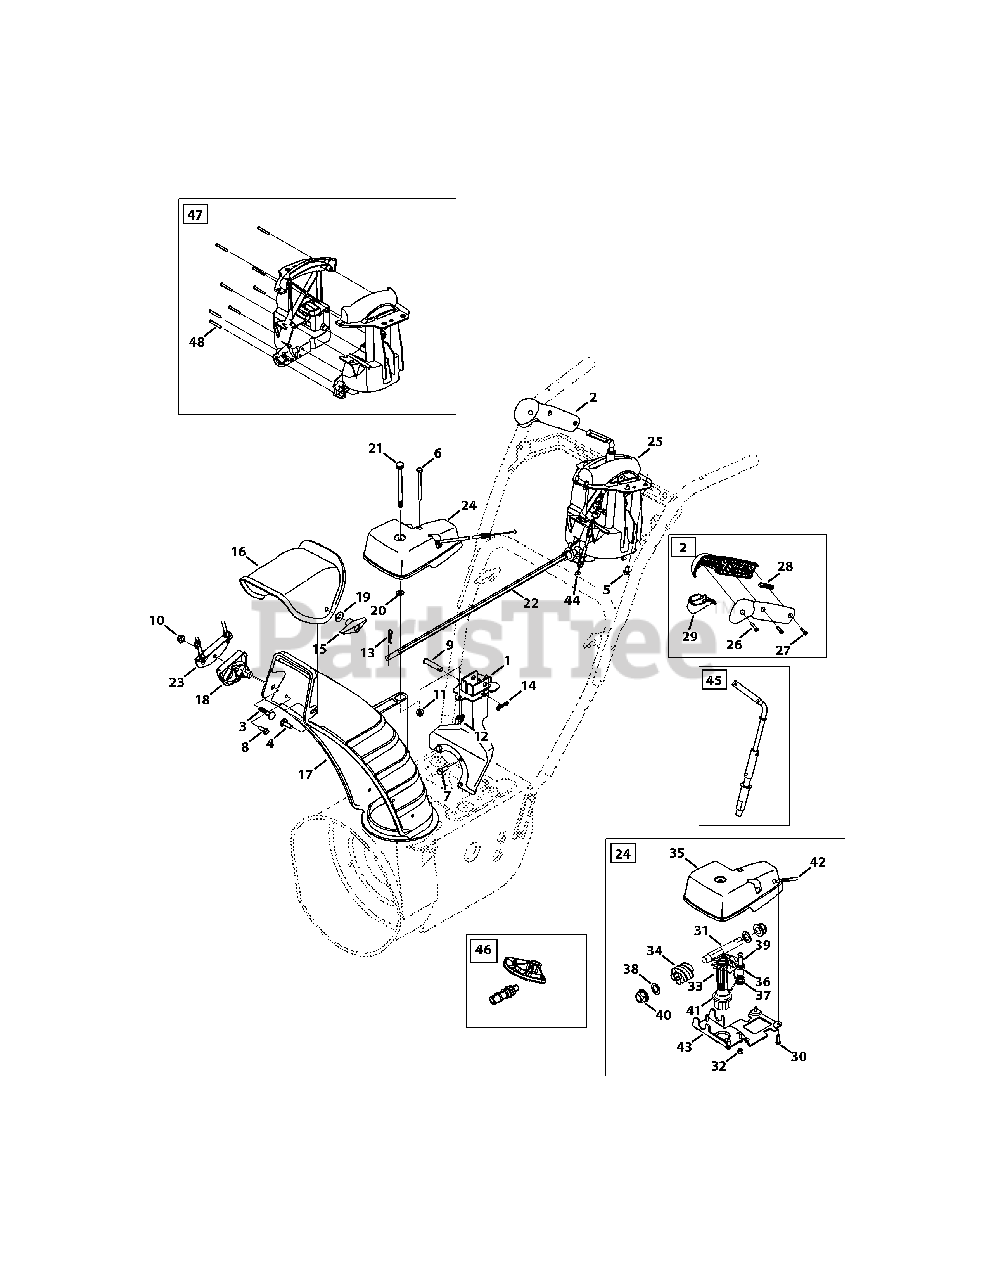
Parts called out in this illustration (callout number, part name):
1	Chute Support Bracket
2	Handle Assembly
3	Bolt, Carriage, 5/16-18 x 1.50
4	Bolt, Carrier, 5/16-18 x 1.00
5	Screw, HL, 1/4-15 x 0.50
6	Hex Head Screw, 1/4-20 x 3.00
7	Hex Head Screw, 5/16-24 x .750
8	Screw, HL, 1/4-15 x 0.750
9	Clevis Pin, 3/8 x 1.87
10	Nut, Flangelock, 5/16-18
11	Nut, Flangelock, 1/4-20
12	Wing Nut, 1/4-20
13	Internal Cotter Pin
14	Bow-Tie Cotter Pin
15	Star Knob, 5/16-18
16	Chute, Upper
17	Chute, Lower
18	Cable Guide, Chute Tilt
19	Washer, Flat, .349 x .879
20	Washer, Flat, .25 x .630
21	Screw, Shoulder, .312 x 3.5 x 1/4-20
22	Chute Rod, 3/8 Hex
23	Cable Bracket
24	Gearbox Assembly, Chute Rotation
25	Chute Control, 4-Way
26	Screw, #8 x 1.00
27	Screw, 8-32 x .750
28	Joystick Plug
29	Joystick Trigger
30	Screw, 12-16 x .75
32	Hexlock Nut, 1/4-28
33	Gear, 14 T
34	Worm
35	Gear Cover
36	Pawl Lock
37	Torsion Spring, .721 ID x .474
38	Washer, Flat, .625 x 1.0 x .067
39	Screw, Shoulder, .340 x .950 x 1/4-28
40	Hex Bearing
41	Flange Bearing
43	Gear Bracket
44	4-Way Cable
44	4-Way Cable w/Clip
45	Shift Assembly
46	Gear Set Assembly
47	Handle Housing Assembly
48	Screw, #8-18 x 1.250
